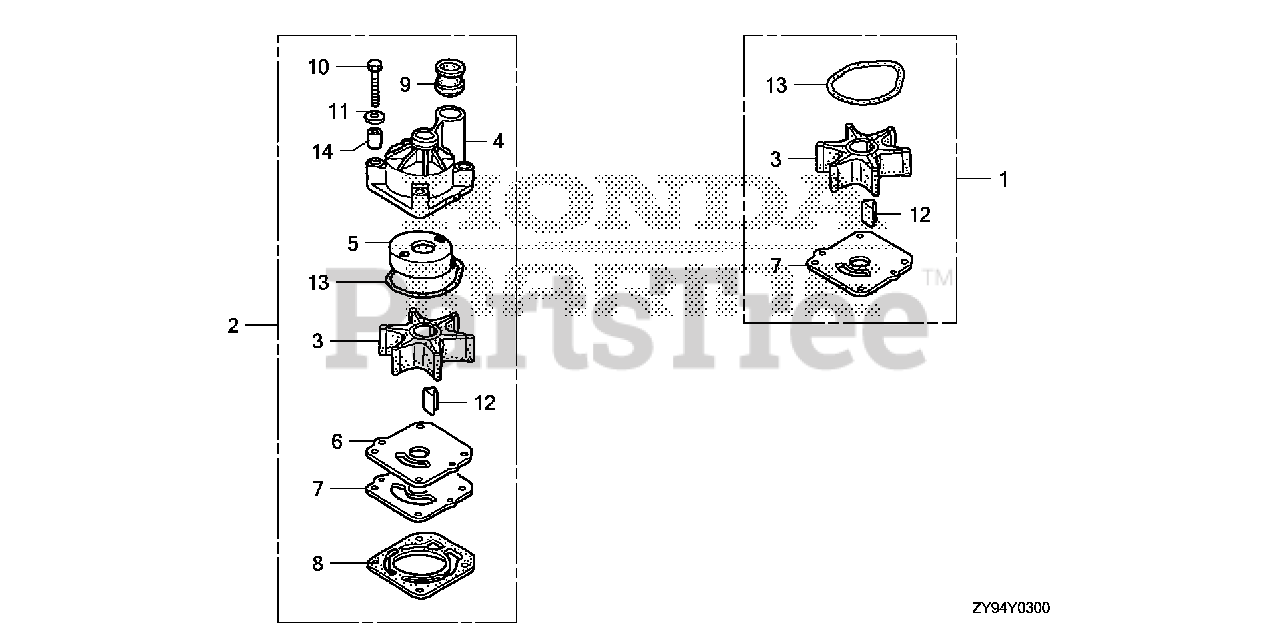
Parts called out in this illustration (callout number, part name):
1	PUMP KIT, IMPELLER
2	PUMP KIT, IMPELLER
3	IMPELLER, PUMP
4	HOUSING, IMPELLER
5	LINER, PUMP
6	COVER, IMPELLER
7	GASKET B, IMPELLER
8	GASKET, WATER PUMP
9	RING, WATER TUBE SEAL
10	BOLT, HEX. (8X55)
11	WASHER (8MM)
12	KEY, WOODRUFF
13	O-RING, WATER PUMP
14	COLLAR, DISTANCE
